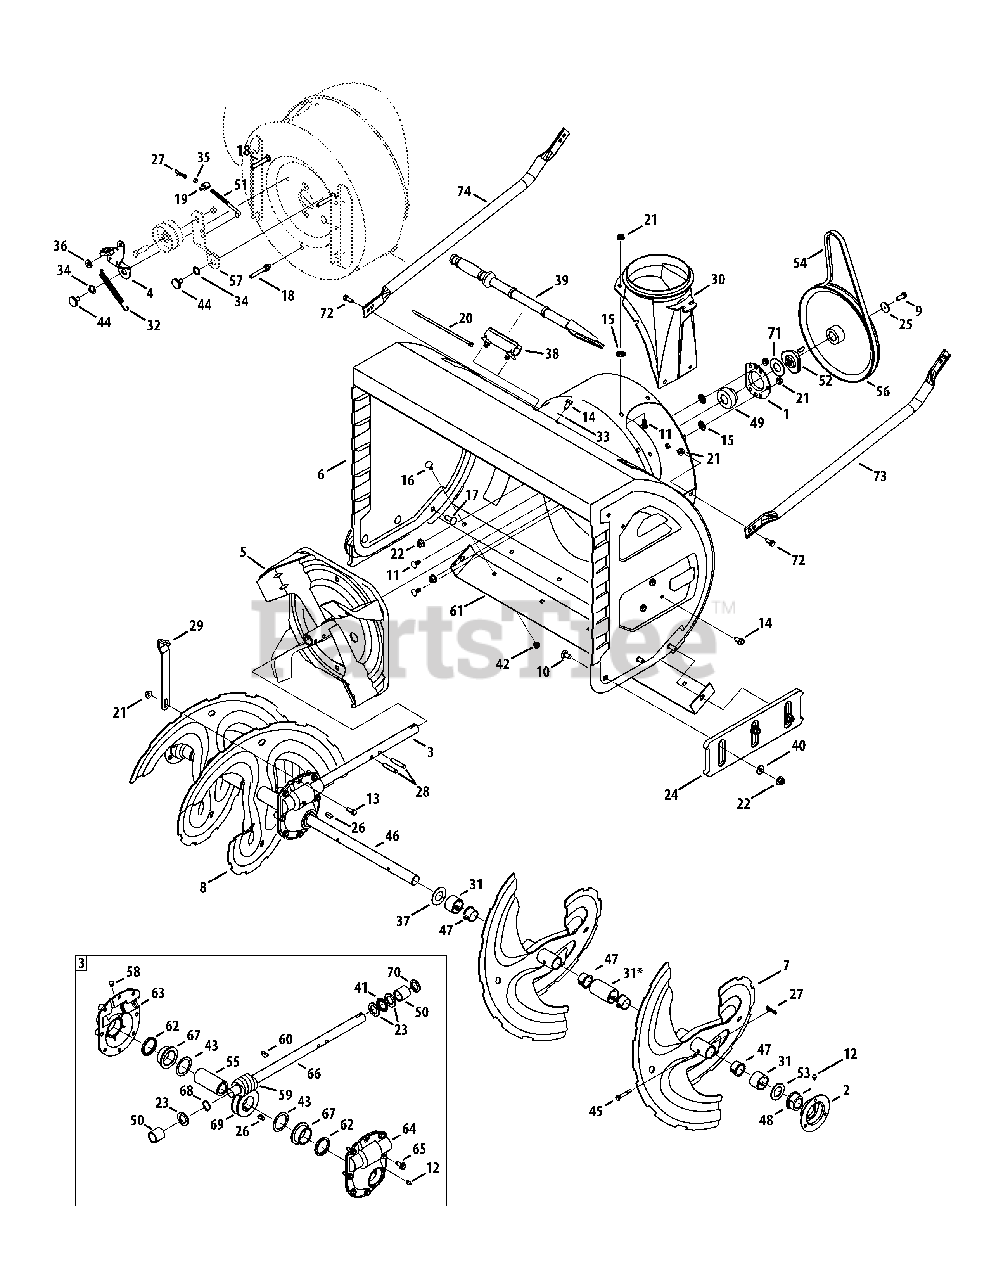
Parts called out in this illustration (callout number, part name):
1	Housing, Bearing
2	Housing, Bearing
3	Gear Box Assembly
4	Bracket Assembly, Auger Brake
5	Impeller, 16"
6	Housing, Auger - 33"
7	Spiral Assembly, LH
8	Spiral Assembly, RH
9	Screw, Hex Cap Lock, 5/16-24
10	Screw, Carriage, 3/8-16 x 1.00
11	Screw, Carriage, 5/16-18 x .75
12	Fitting, Lube
13	Screw, Hex Cap, 5/16-18 x 1.0 Gr5
14	Screw, 5/16-18 x .750
15	Nut, Push
16	Screw, Carriage, 5/16-18 x .75
17	Screw, Carriage, 3/8-16 x 1.25
18	Screw w/Stud, 5/16-18 x .4300
20	Tie Strap
21	Nut, Hex Flange Lock, 5/16-18
22	Nut, Hex Flange Lock, 3/8-16
23	Wash, Flat, .88 ID x .38 OD
24	Shoe Skid, Deluxe - Blue
25	Washer, Flat, .34 x 1.5 x .15 Ht.
26	Key, Woodruff, 1/4 x 3/4
27	Pin, Bow-tie Cotter
28	Pin, Spiral, 5/16 x 1.75
29	Bracket, Gear Box Support
30	Adapter, Chute, 6"
31	Spacer, 1.0 x 1.5 x 2.5 Lg - 33" ONLY
32	Spring, Extension
33	Washer, Flat, .349 x .879 .063
34	Washer, Wave, .625 x .885 x .015
35	Jam Nut, 5/16-18
36	Washer, .344 x .75 x .12
37	Washer, 1.01 x 1.86 x .06
38	Clip, Mounting
39	Tool, Clean-out
40	Wash, Flat, .385 x .870 x .092
41	Bearing, Thrust
42	Nut, Hex, 5/16-18 Stainless
43	Wash, Flat, 1.52ID x 2.0 OD
44	Screw, Shoulder, .625 x .17
45	Pin, Shear, .25 x 1.75
46	Shaft, Spiral, - 33" ONLY
47	Bushing, Flange,
48	Bearing, Flange w/Flats
49	Bearing, Self Aligning
51	Rod, Auger Idler
52	Adapter, Pulley w/Pins
53	Spacer, 1.004 x 1.375 x .25
54	V-Belt, 1/2 x 42
55	Shaft, Gear, Worm
56	Pulley, Auger Drive, 10.0
57	Bracket, Auger Idler
59	Gear, Worm
60	Key, Hi Pro, 3/16 x 3/4
61	Plate, Shave - 33" ONLY
63	Hsg, Ass’y, Auger RH (Incl. Ref. 62 & 67)
64	Hsg, Ass’y, Auger LH (Incl. Ref. 62 & 67)
65	Screw, LD, 5/16-18 x .750
66	Shaft, Drive, Auger
67	Flange Bearing
68	External, Retaining, Ring
69	Gear, Worm, LH
70	Seal, Oil
71	Washer, Flat, .76 x 1.49 x .06
72	Hex Cap Screw, 5/16-18 x .75
73	Support Tube, LH
74	Support Tube, RH
